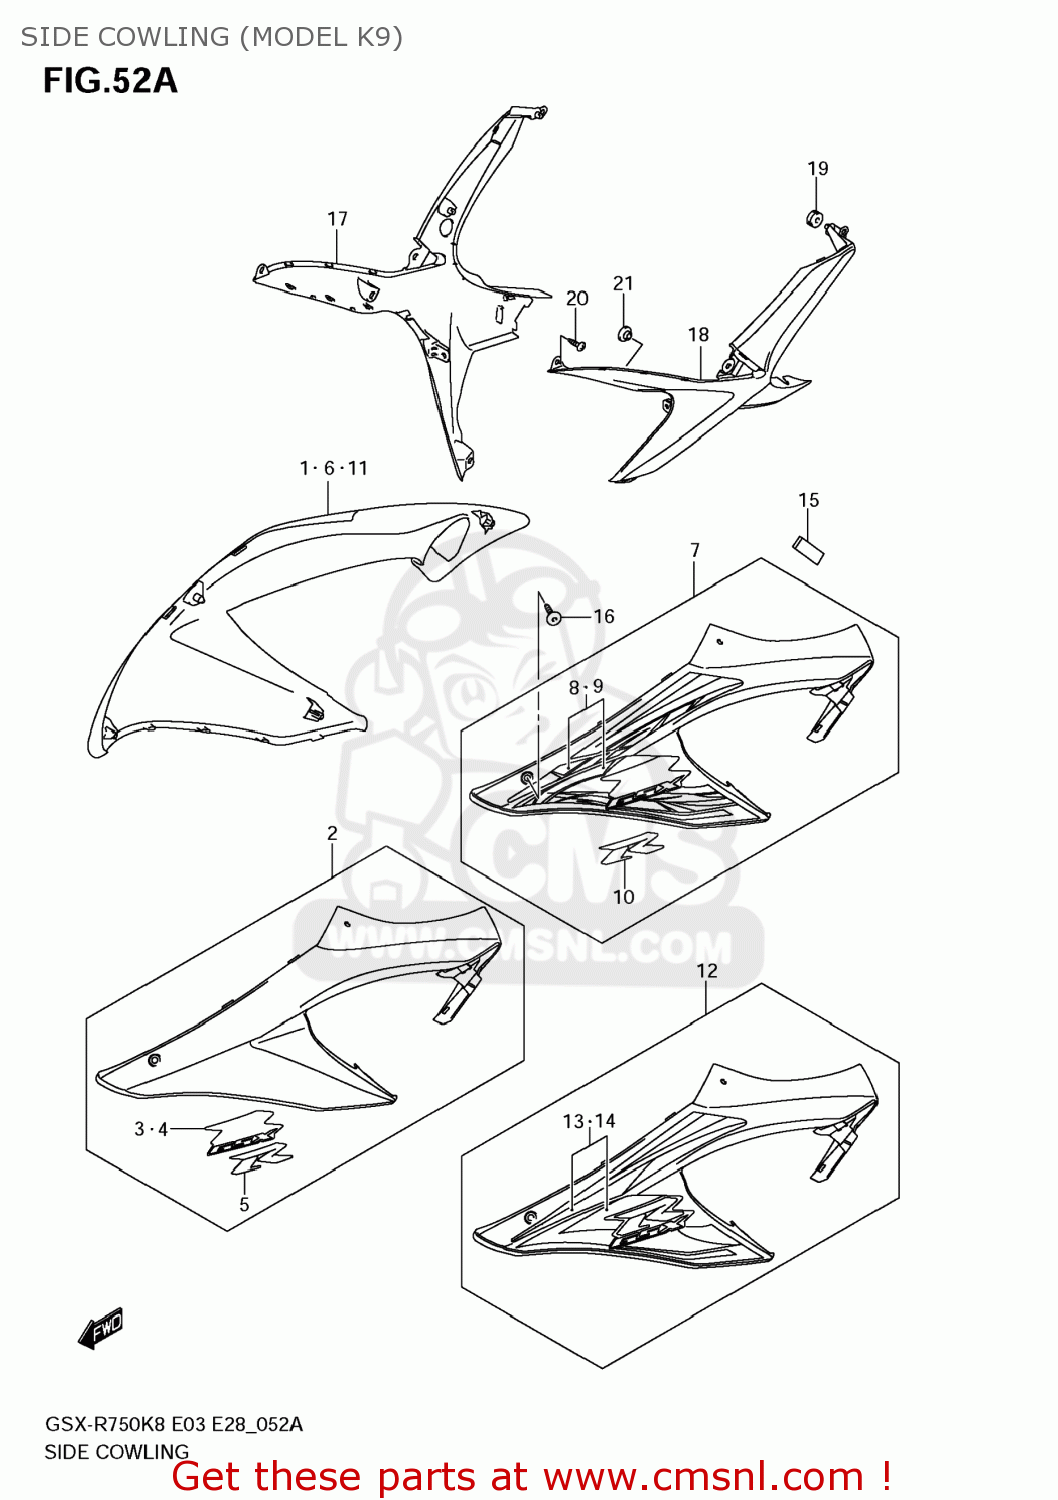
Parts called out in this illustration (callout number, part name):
1	COWLING,SIDE,R(BLACK)
2	COWLING,SIDE,L(BLACK)
3	EMBLEM,GSXR,R
4	EMBLEM,GSXR,L
5	EMBLEM,R
6	COWLING,SIDE,R(GOLD)
7	COWLING,SIDE,L(GOLD)
8	TAPE SET,COWL SIDE,R
9	TAPE SET,COWL SIDE,L
10	EMBLEM,R
11	COWLING,SIDE,R(BLUE)
12	COWLING,SIDE,L(BLUE)
13	TAPE SET,COWL SIDE,R
14	TAPE SET,COWL SIDE,L
15	CUSHION,SIDE COWL
16	SCREW(5X16)
17	COVER,UNDER COWL,R
18	COVER,UNDER COWL,L
19	CUSHION
20	SCREW
21	CUSHION
